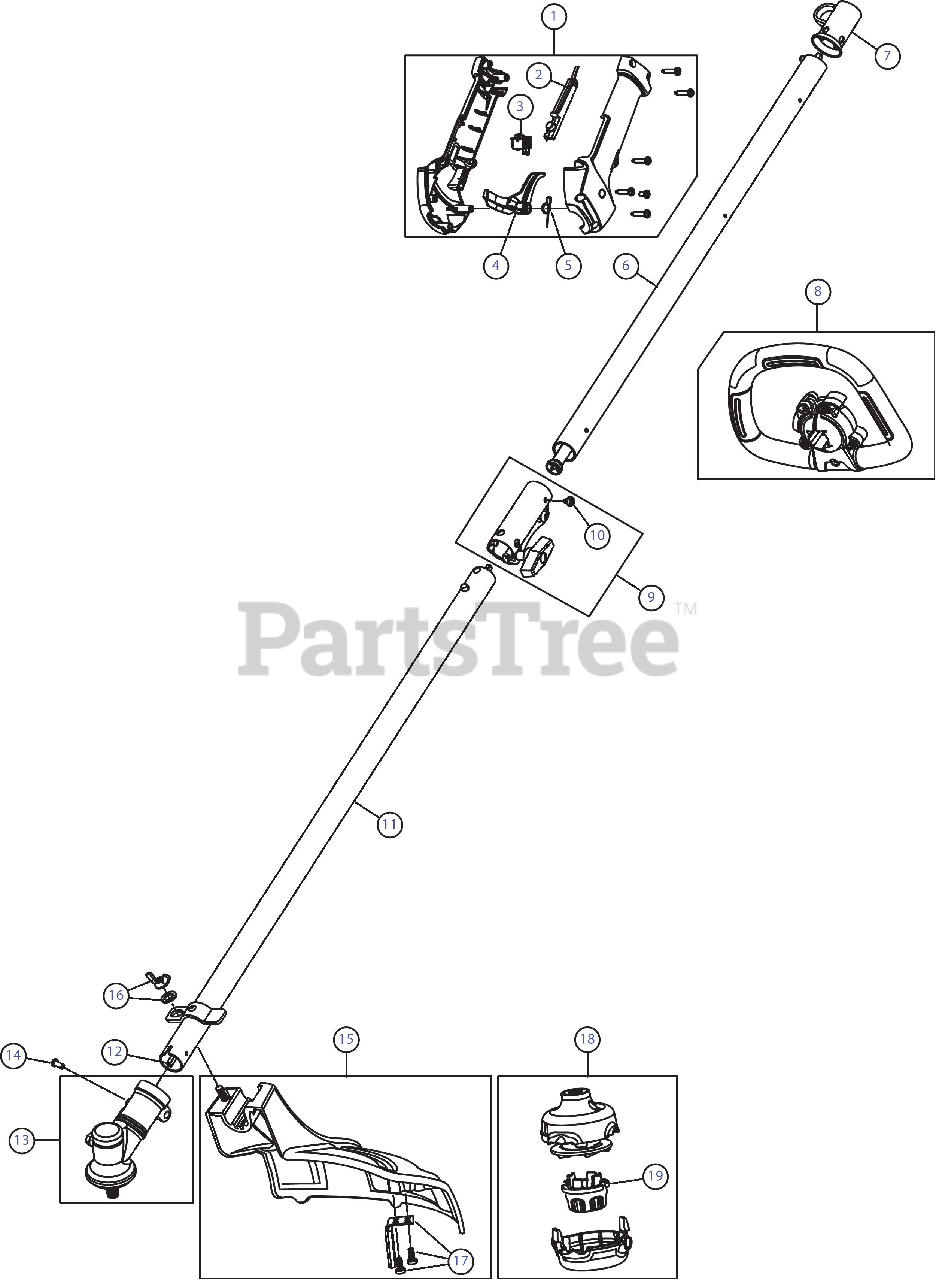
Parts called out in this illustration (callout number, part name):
1	Throttle Housing Assembly
2	Throttle Trigger Lock-Out
3	Trigger Switch Assembly
4	Throttle Trigger Spring
5	Throttle Trigger
6	Upper Shaft Housing Assembly
7	Hanger
8	Handle
9	Split Boom Coupler
10	Anti-Rotation Screw
11	Lower Shaft Housing Assembly
12	Lower Flexible Drive Shaft
13	Gearbox Assembly
14	Gearbox Anti-Rotation Screw
15	Shield Assembly
16	Shield Mounting Hardware
17	Blade Assembly
18	Cutting Head Assembly
19	Bump Knob
